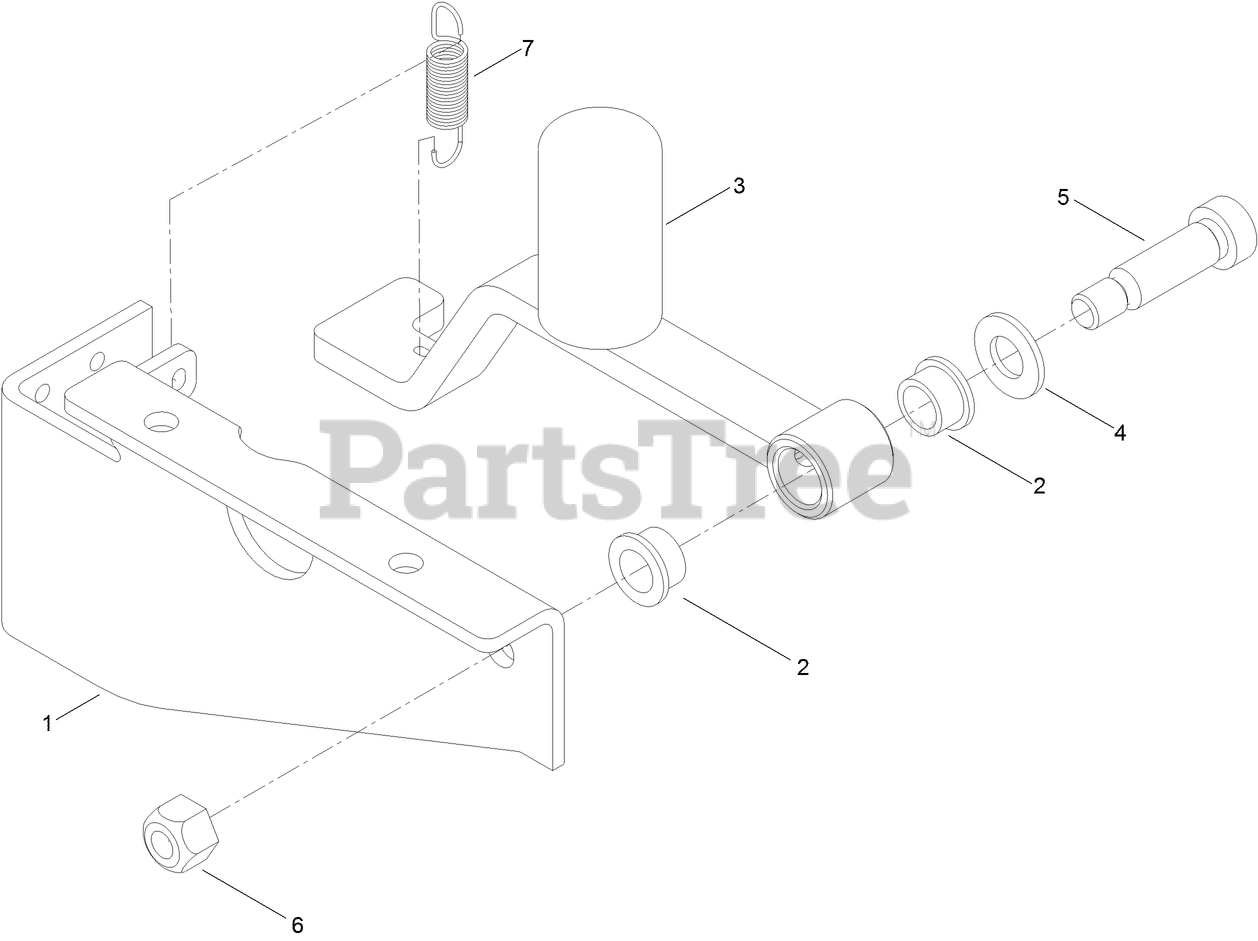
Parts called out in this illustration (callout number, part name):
1	BRACKET-SWITCH, LH
2	BUSHING-FLANGED
3	LEVER-SWITCH, AUXILIARY
4	WASHER-FLAT
5	BOLT-SHOULDER
6	NUT-LOCK, NI
7	SPRING
